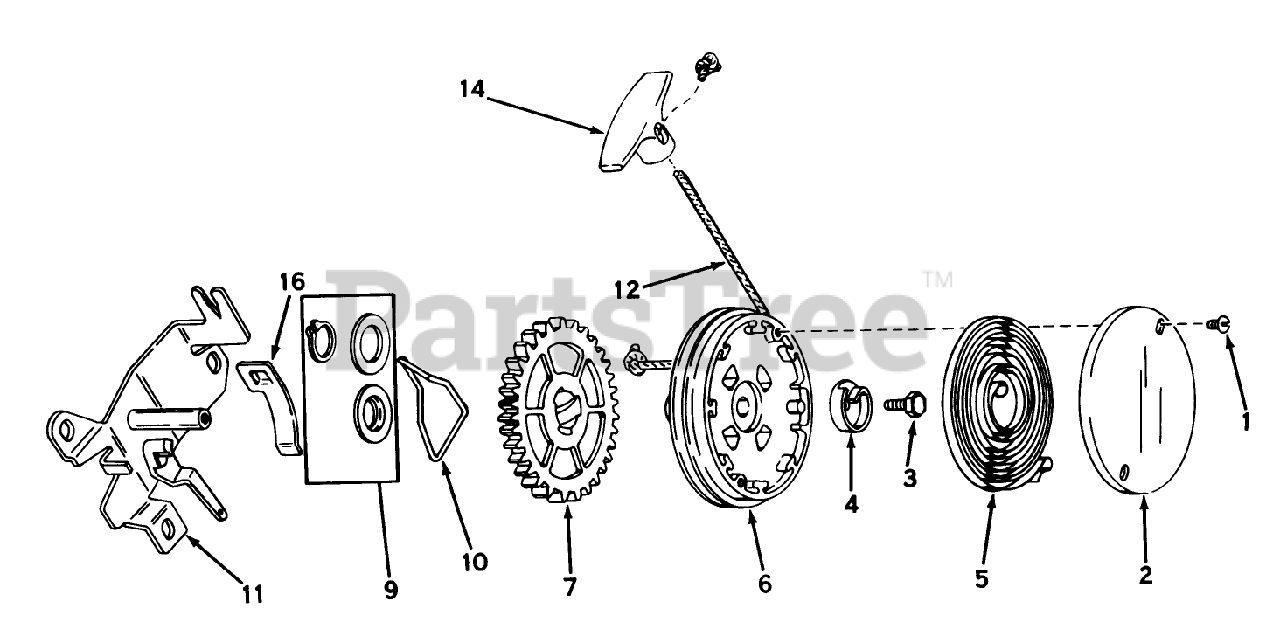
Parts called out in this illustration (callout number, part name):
2	Cover, Spring
3	Screw, Hex Washer Head
4	Hub Spring
5	Spring, Rewind
6	Pulley Assy. (Incl. Ref. #9)
9	Kit, Thrust Wash. & Snap Rg.
11	Bracket Assy., Mounting
12	Rope-Starter
14	Handle-Starter
16	Clip Rope
